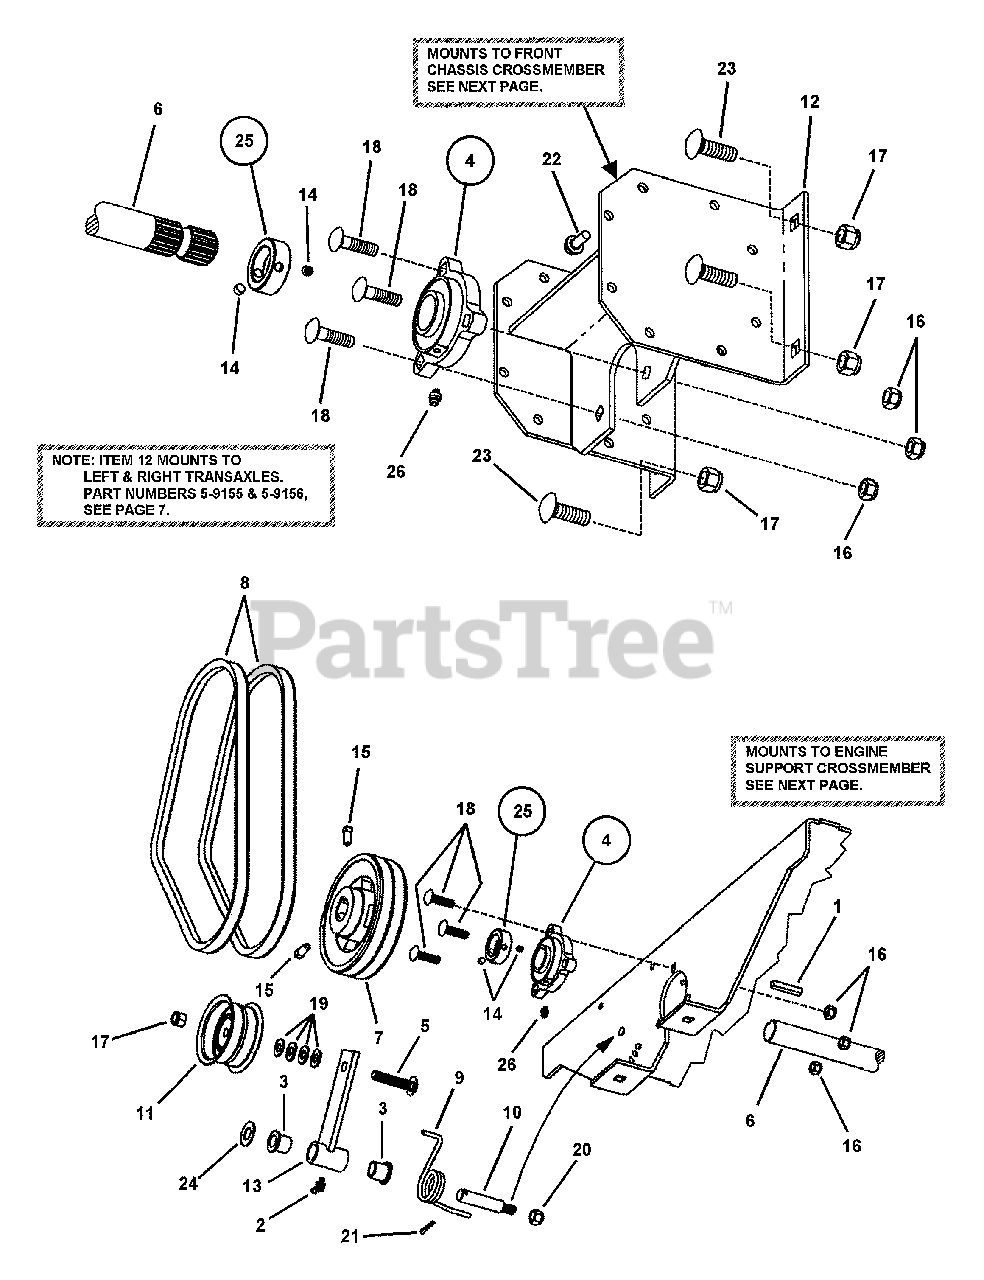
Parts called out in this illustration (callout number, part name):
1	KEY, 1/4" Square x 2"
2	FITTING, Lube (45 degree, for 3/16" hole)
3	BUSHING
4	ASSEMBLY, Bearing
5	BOLT, 3/8-16 x 2" Carriage, Grade 2
6	DRIVE SHAFT, Deck (1" Diameter, 15 Spline)
7	PULLEY, Double V (5.45 O.D., A Section)
8	BELT, Deck Drive (HA 36.5" Eff. Length)
9	SPRING, Tension
10	PIN, 3/8-24 UNF
11	FLAT IDLER, 2.75 O.D. x 1-1/4" Wide
12	WELDMENT, Bearing Mount
13	IDLER ARM, Straight (Weldment)
14	SET SCREW, 1/4-20 x 1/4" Cone Point
15	SET SCREW, 5/16-18 x 5/8 Knurled Cup Point
16	NUT, 5/16-18 HEX NYLON LOCK
17	NUT, 3/8-16 HEX NYLON LOCK
18	BOLT, 5/16-18 x 1-1/4", Square Neck Carriage Grade 5
19	WASHER, 3/8" Flat
20	NUT, 3/8-24 Hex Nyloc
21	COTTER-PIN, 1/8 x 3/4"
22	SCREW, 1/4-20 x 5/8", Hex Flange Lock, Grade 5
23	BOLT, 3/8-16 x 1-1/4" Carriage, Grade 5
24	WASHER, 9/16 Flat
25	ASSEMBLY, Lock Collar, 1" (with 1/4" Set Screw, item 14)
26	LUBE FITTING, Straight (press-fit for .187 dia. Hole)
